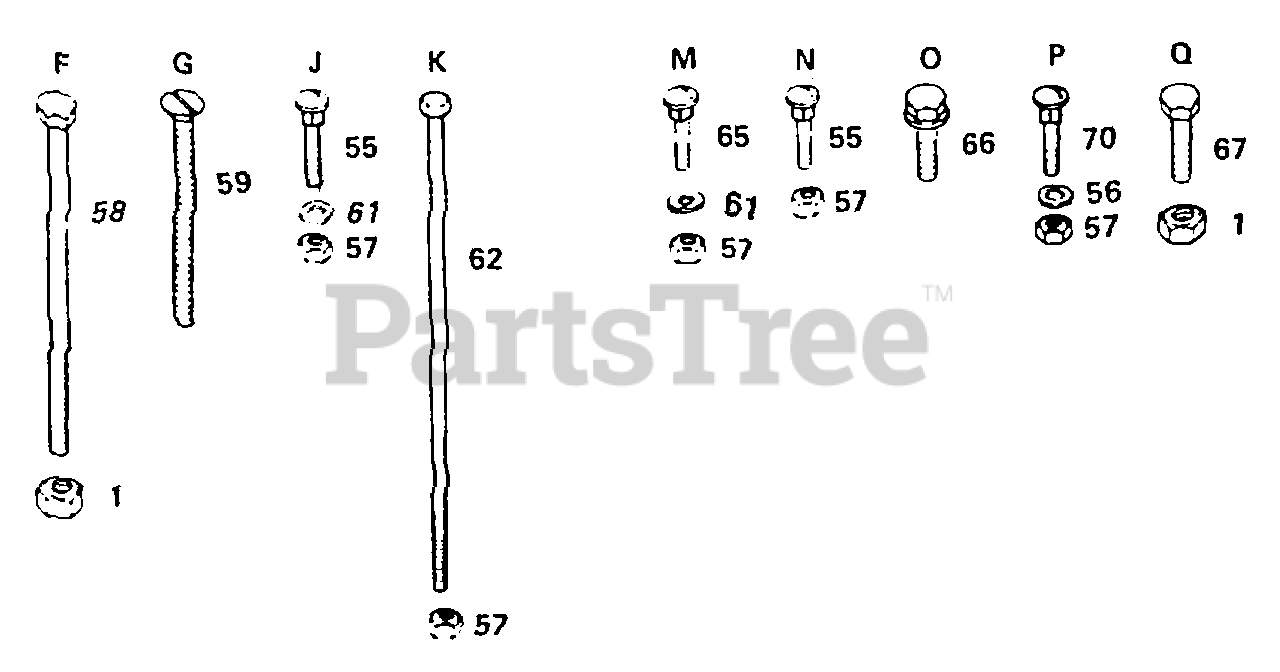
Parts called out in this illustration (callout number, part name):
55	BOLT
56	WASHER
58	BOLT - HEX 3/8 - 16 X 3
59	SCREW YT
61	WASHER M
62	BOLT
65	BOLT
66	SCREW
67	BOLT
